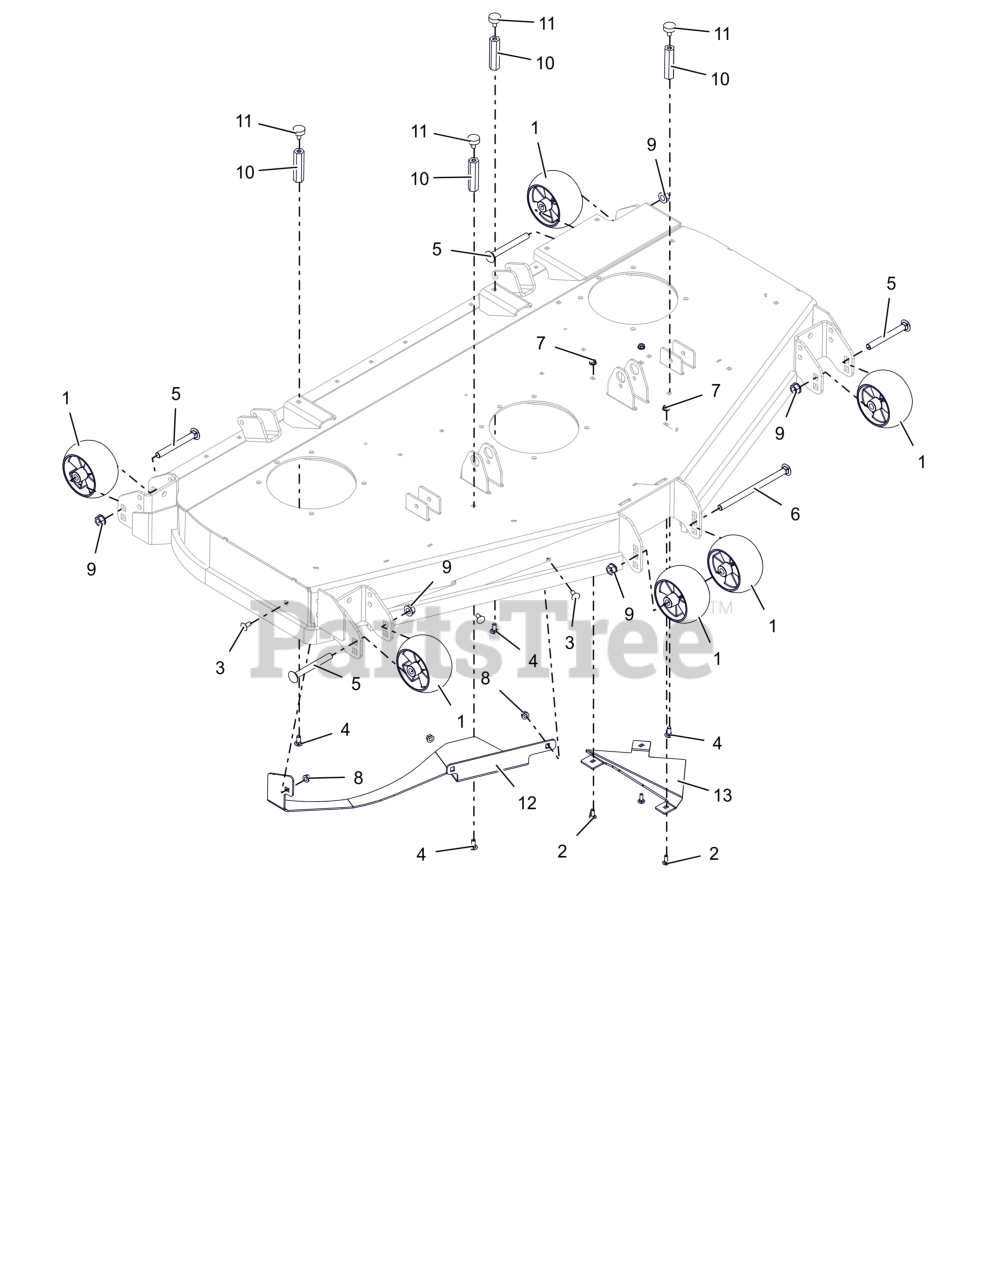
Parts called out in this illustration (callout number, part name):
1	WHEEL, ANTI SCALP - 5X3 CTR W/RIBS
2	BLT, RHSN .25-20X.750 G5 ZCC
3	BLT, RHSSN.31-18X.750 G5 ZCC
4	BTL,RHSN .313-18 X 0.75 G5 ZCC LT
5	BOLT, RHNS .50-13X4.50 G5 ZCC NS
6	BOLT, RHNS .50-13X8.00 G5 ZCC NS
7	NUT-LK-CTR-FLG .25-20 ZC120
8	NUT,LK-CTR-FLG .31-18 GF ZCC
9	NUT-LK-CTR-FLG .500-13 GG ZCC
10	NUT, COUPLING .31-18 X 3.00
11	BUMPER, RUBBER
12	DEFLECTOR, BAFFLE BOLT-IN (RED)
13	BAFFLE- INSERT TRIANGLE
